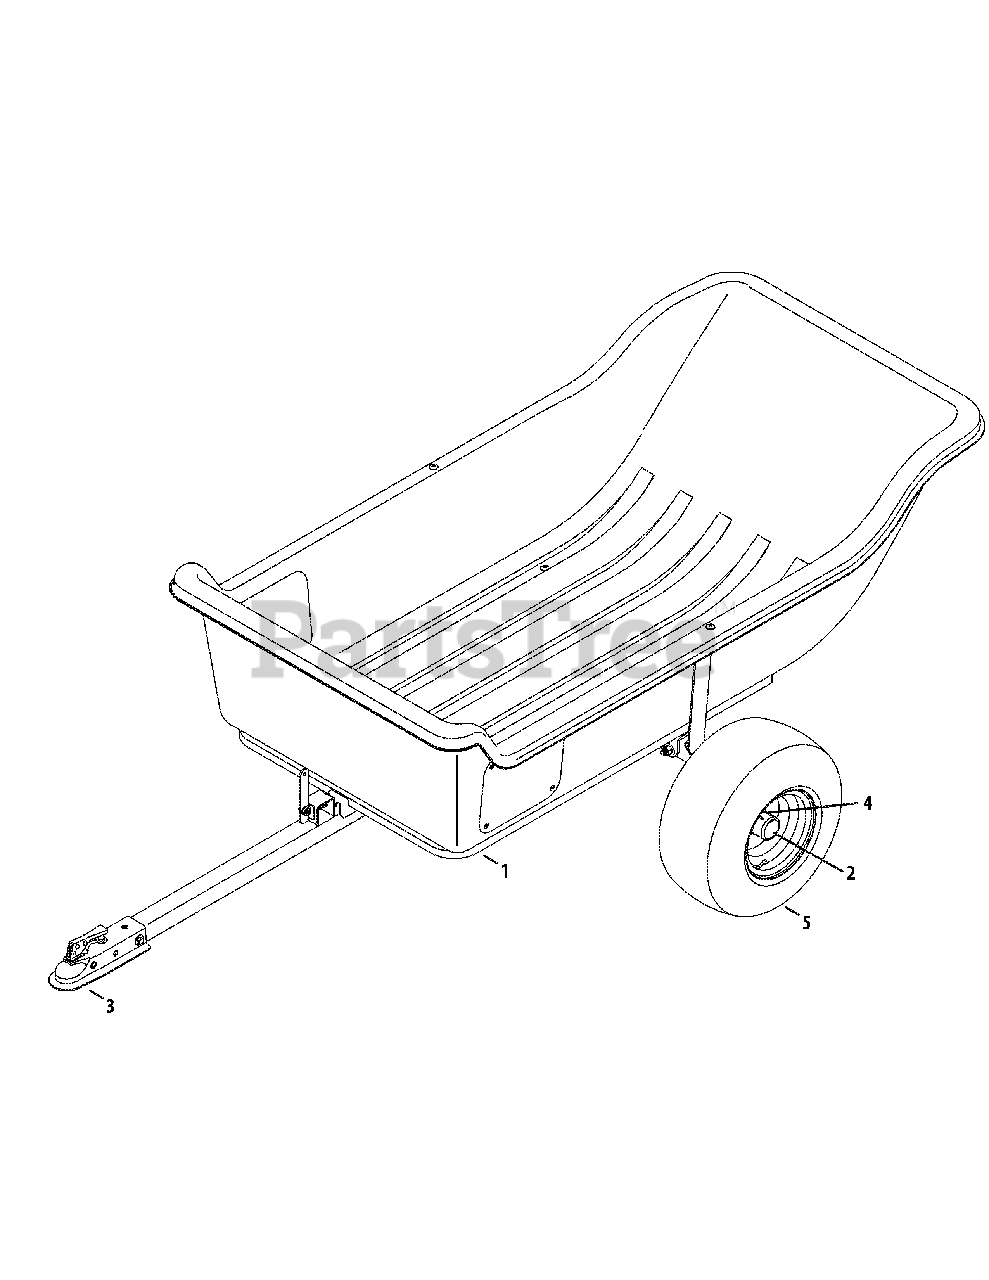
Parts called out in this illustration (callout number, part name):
1	Trailer Attachment Assembly
3	Hitch Coupler
4	Bearing Kit
5	Wheel Assembly
